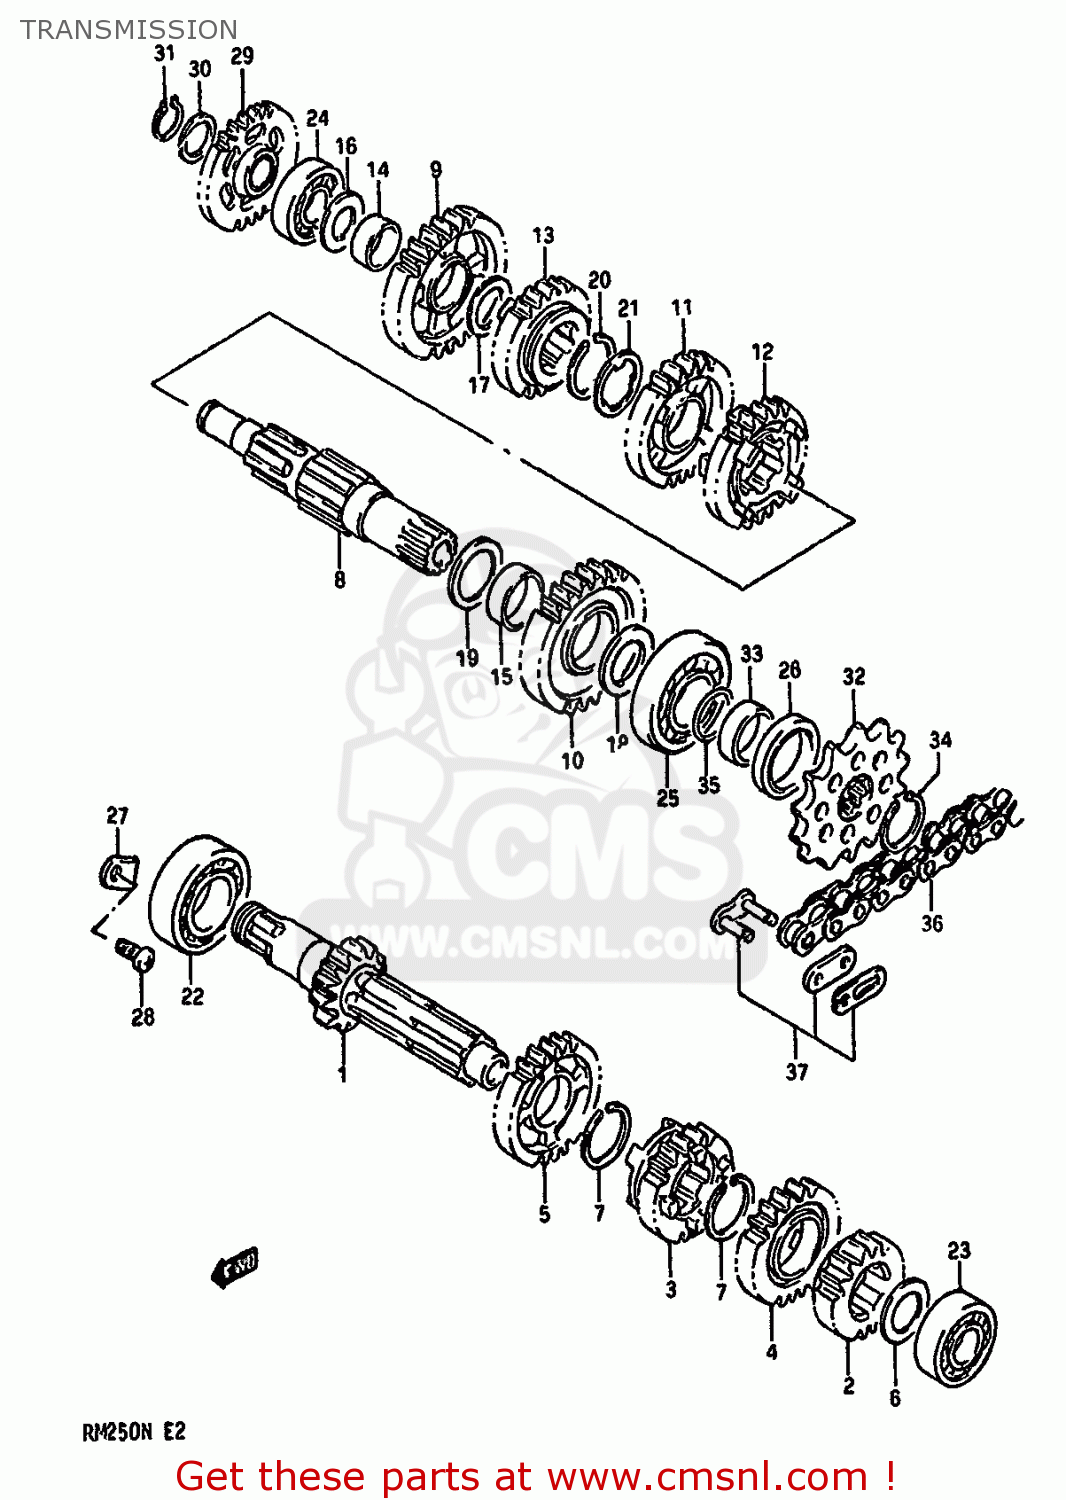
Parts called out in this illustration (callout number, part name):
1	SHAFT,COUNTER
2	GEAR,2ND DRIVE(NT:15)
3	GEAR,THIRD DRIVE
4	GEAR,FOURTH DRIVE
5	GEAR,FIFTH DRIVE
6	WASHER,THRUST
7	CIRCLIP
8	SHAFT,DRIVE
9	GEAR,FIRST DRIVEN
10	GEAR,2ND DRIVEN(NT:26)
11	GEAR,THIRD DRIVEN
12	GEAR,FOURTH DRIVEN
13	GEAR,FIFTH DRIVEN
14	BUSH(20X24X10)
15	BUSH(25X28X10)
16	WASHER,THRUST
17	WASHER
18	WASHER
19	WASHER
20	CIRCLIP
21	WASHER,LOCK
22	BEARING(25X52X15)
23	BEARING(17X40X12)
24	BEARING(17X40X12)
25	BEARING(22X56X15)
26	SEAL,OIL(28X38X6)
27	RETAINER,SHIFT CAM,R BEARING
28	SCREW 6X12
29	GEAR,KICK STARTER IDLE
30	SHIM
31	CIRCLIP
32	SPROCKET,ENGINE
33	SPACER,ENGINE SPROCKET
34	CIRCLIP
35	O RING(D:1.9,ID:21.8)
36	CHAIN ASSEMBLY,DRIVE
37	JOINT ASSEMBLY,CHAIN
